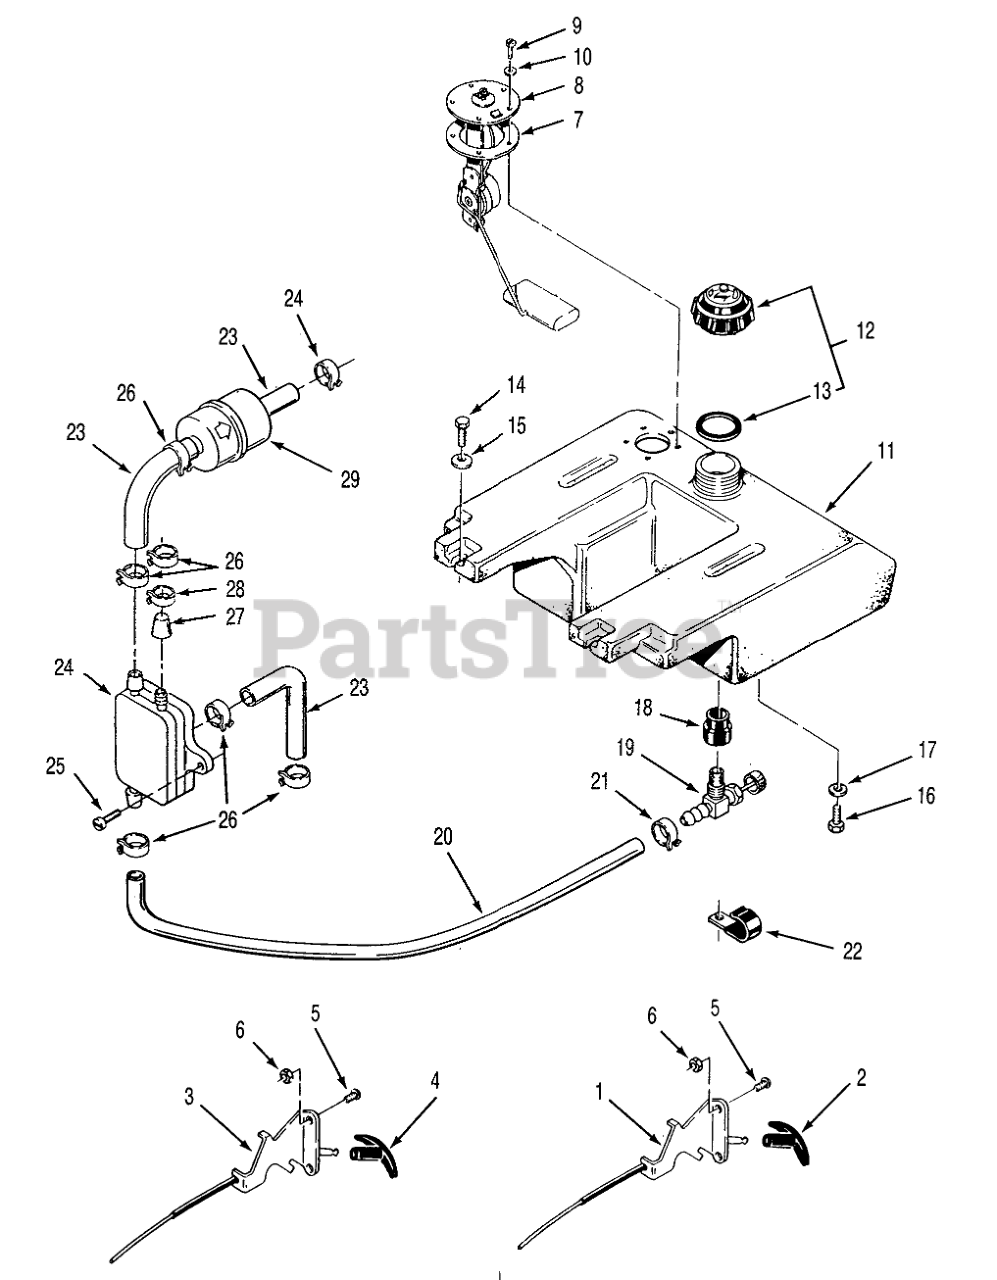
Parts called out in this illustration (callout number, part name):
1	Throttle Control
2	KNOB-THROTTLE
3	CONTROL-CHOKE
4	KNOB-CHOKE
5	SCRW-PHC
6	Nut
7	GASKET-SENDER, FUEL
8	SENDER-FUEL LEVEL
9	Screw
10	Lockwasher
11	Fuel Tank (Includes items 20 & 21)
12	Fuel Cap (Includes item 15)
13	GASKET-GAS CAP
14	Bolt
15	Washer
16	Bolt
17	Lockwasher
18	BUSHING
19	VALVE-FUEL
20	Line-Fuel 53"
21	Clamp
22	Clamp
23	Hose
24	Fuel Pump
25	Screw
26	Clamp
27	Cap
28	Clamp
29	X-REF 71-5960
